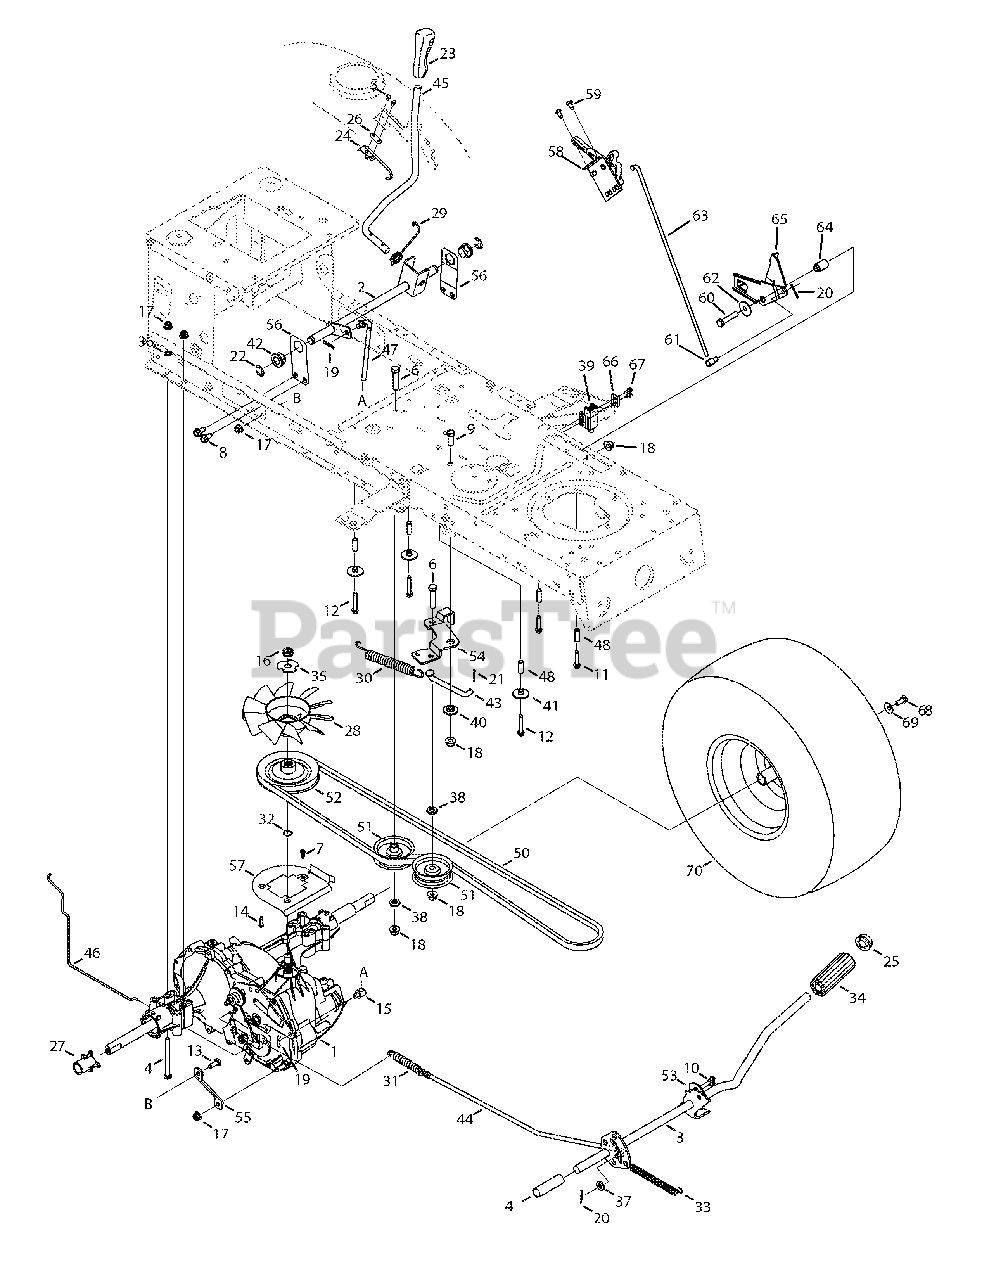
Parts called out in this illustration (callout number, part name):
1	Transmission Assembly, Hydro
2	Control Assembly, Hydrostatic
5	Screw, #8-18, 0.500
6	Hex Screw, 3/8-16, 1.75
7	Screw, B, #10-16, 0.500
8	Screw, 5/16-18, 0.750
9	Hex Screw, 3/8-16, 1.00, Gr5
10	Screw, 5/16-18, 0.625
11	Screw, 1/4-20, 1.250
12	Screw, 1/4-20, 1.625
13	Hex Screw, 5/16-18, .75, Gr5
14	Screw, #10-24 x 0.75
15	Ferrule, 5/16-24 x .312 Dia.
16	Nut, Hex Lock, 1/2-20, Gr5
17	Nut, Flange Lock, 5/16-18, Grf
18	Nut, Flange Lock, 3/8-16, Grf
19	Pin, Cotter, .072 Dia. x 1.13
20	Pin, Cotter, 3/32, 1.0
21	Pin, Cotter, 3/32 x 1.25
22	Ring, E-Type, .625 Dia.
23	Grip, Handle, 1/2
24	Spring Switch, Hydro
25	Push Cap, 5/8
26	Plate, Insulator Nut
27	Sleeve, .765 x 1.50
28	Fan, Hydro
29	Spring, Torsion
30	Spring, Extension, .75 OD x 6.02
31	Spring, Extension, .59 OD x 4.00
32	Ring, Wire
33	Spring, Extension, .50 Dia x 6.37
34	Foot Pad, 4.0
35	Hydro Trans Lock Washer
36	Washer, Lock 5/16 Ext. Tooth
37	Washer, Flat, .344 x .750 x .120
38	Washer, Flat, .407x.812x.135
39	Switch, Interlock
40	Spacer, Shoulder, .625 ID x .169
41	Shoulder Spacer, .375 x .274
42	Bearing, Hex Flange
43	Declutching Rod
44	Brake Rod, Hydrostatic
45	Control Handle, Hydrostatic
46	Bypass Rod, Hydrostatic
47	Control Rod, Hydrostatic
48	Spacer, .260 x .372 x 1.030
49	Spacer, .640 x .76 x 2.63
50	Belt, V-Type
51	Idler Pulley, Flat 2.75 OD
52	Pulley, Input, 5.0 Dia.
59	Screw, 1/4-14, 0.625
60	Hex Screw, 3/8-16, 2.00
61	Ferrule 1/4-20
62	Washer, Flat, .411 x 1.25 x .100
63	Control Rod
64	Spacer, Flange, .390 x .671 x .95
65	Latch Assembly, Engagement
66	Plate, Switch
67	Pop Rivet, .187 dia.
68	Screw, 5/16-24, .750, Gr5
69	Bell Washer, .34 x .872 x .060
